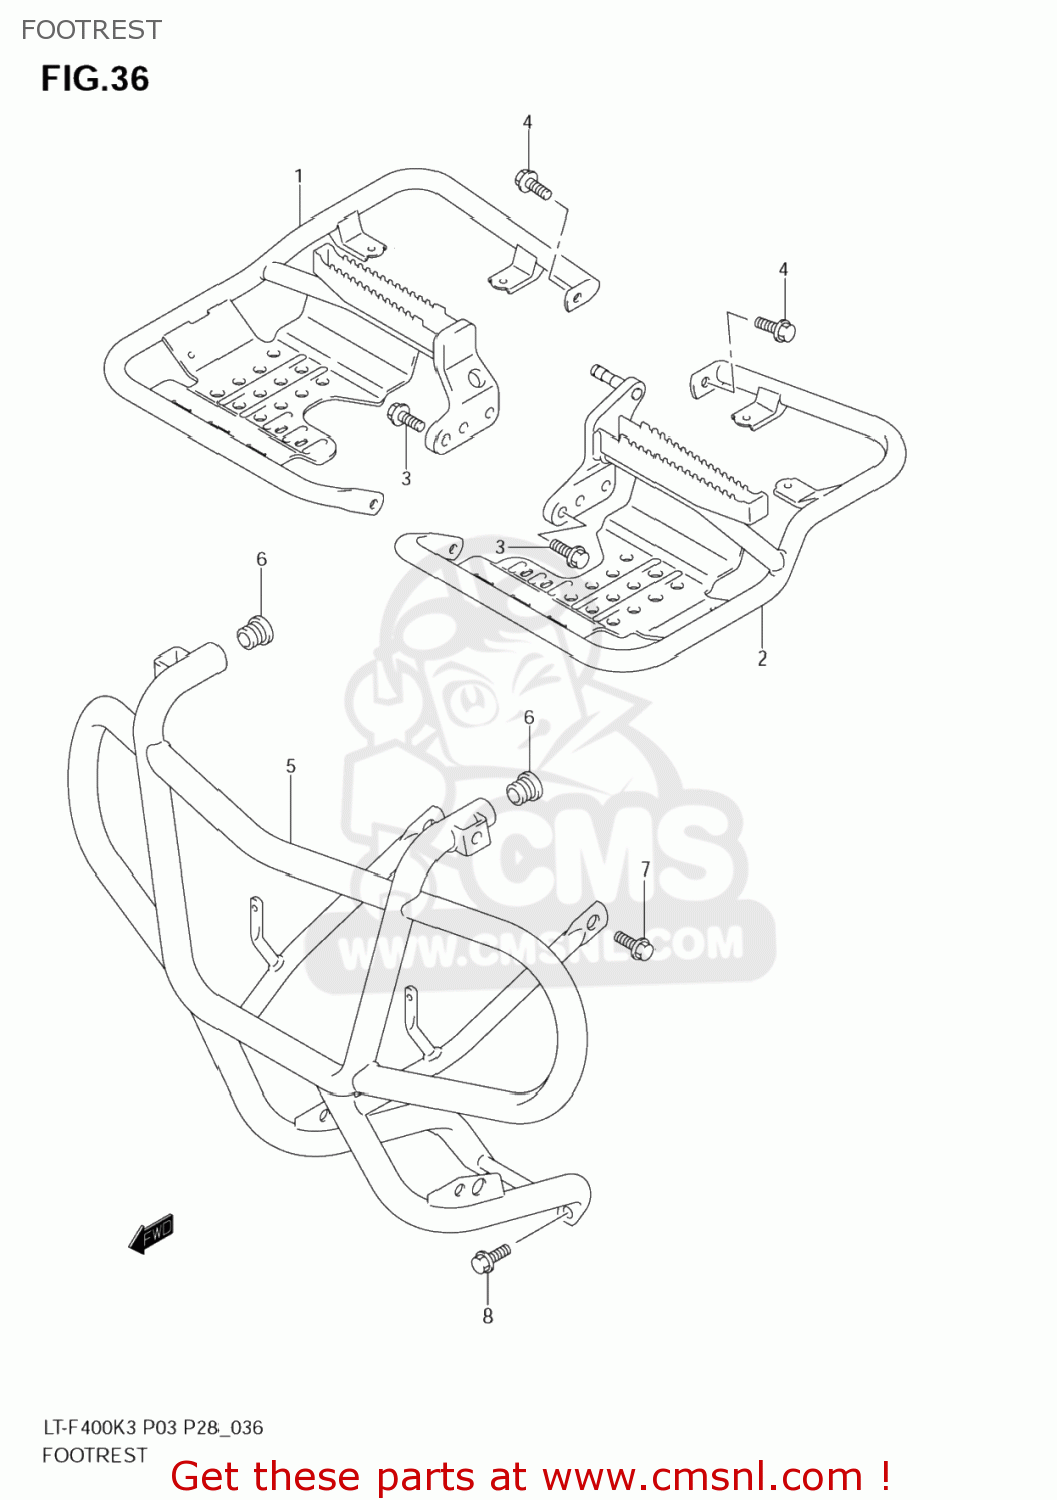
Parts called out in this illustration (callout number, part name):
1	FOOTREST,R
2	FOOTREST COMP,
3	BOLT(10X25)
4	BOLT
5	GRIP,FR
6	CAP,FR GRIP
7	BOLT
8	BOLT(8X16)
